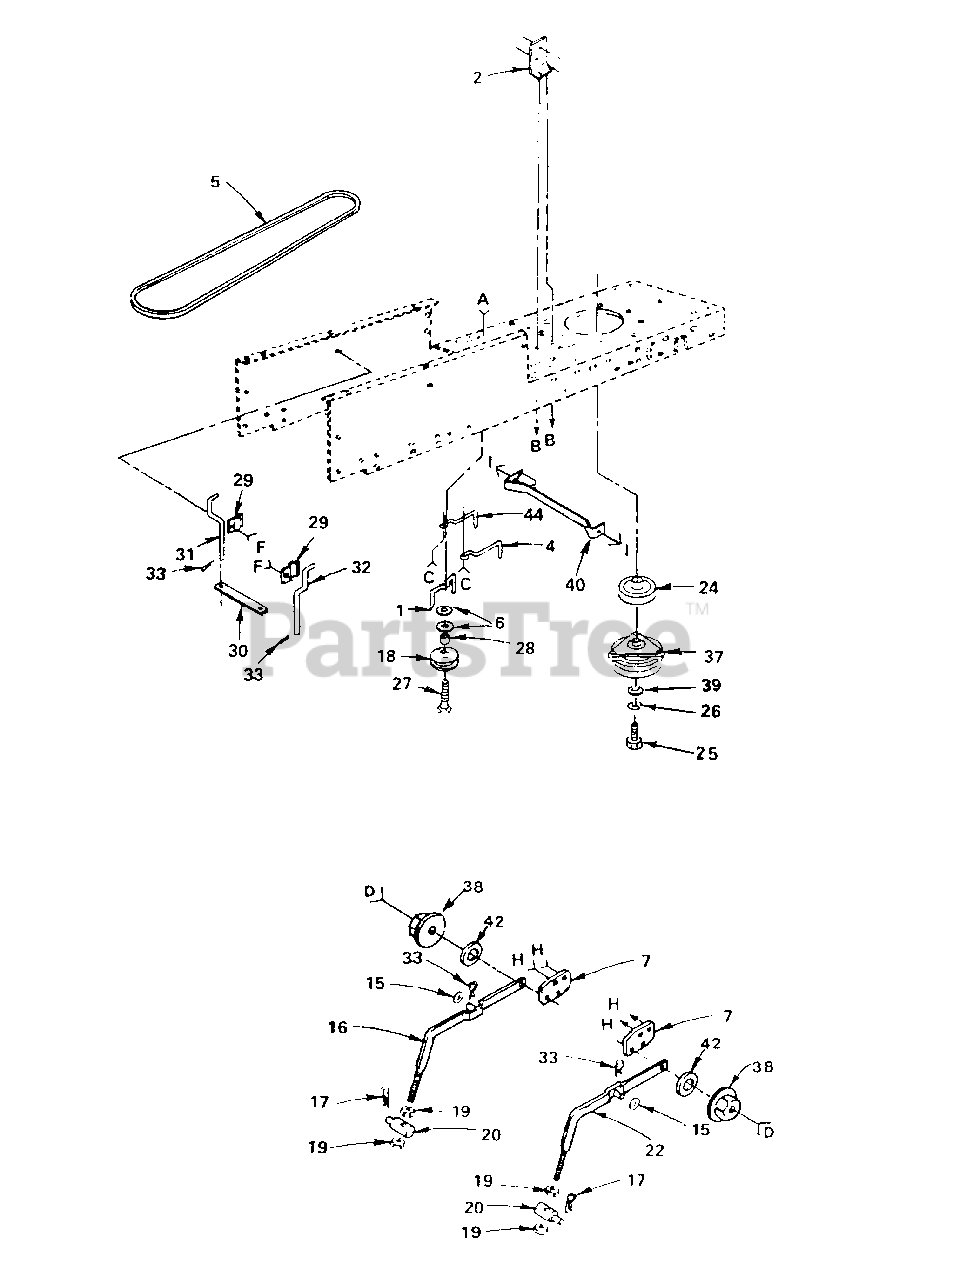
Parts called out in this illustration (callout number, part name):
1	Retainer, Belt
2	Bracket, Switch
4	Keeper, Belt, Engine
5	V-Belt, Drive
6	Washer, 13/32 x 13/16 x 16 Ga.
7	Bracket, Suspension
15	Washer, 17/32 x 15/16 x 16 Ga.
16	Arm Assembly, Suspension, L.H.
17	Retainer, Spring
18	Idler, Flat
19	Nut, Hex 1/2 -13
20	Trunnion, Lift, Lower
22	Arm Assembly, Suspension, R.H.
24	Pulley, Engine
25	Bolt, Hex 7/16 - 20 x 4
26	Washer, Lock 7/16
27	Bolt, Hex 3/8-16 x 2 - 3/4
28	Spacer
30	Strap, Locator
31	Keeper, Belt, L.H.
32	Keeper, Belt, R.H.
33	Spring, Retainer
37	Clutch, Electric
38	Nut, Centerlock Flange - 3/8-16
39	Washer, 15/32 x 1-1/2 x 1/4
40	Retainer, Clutch
42	Spring Washer
44	Keeper, Belt, Engine
